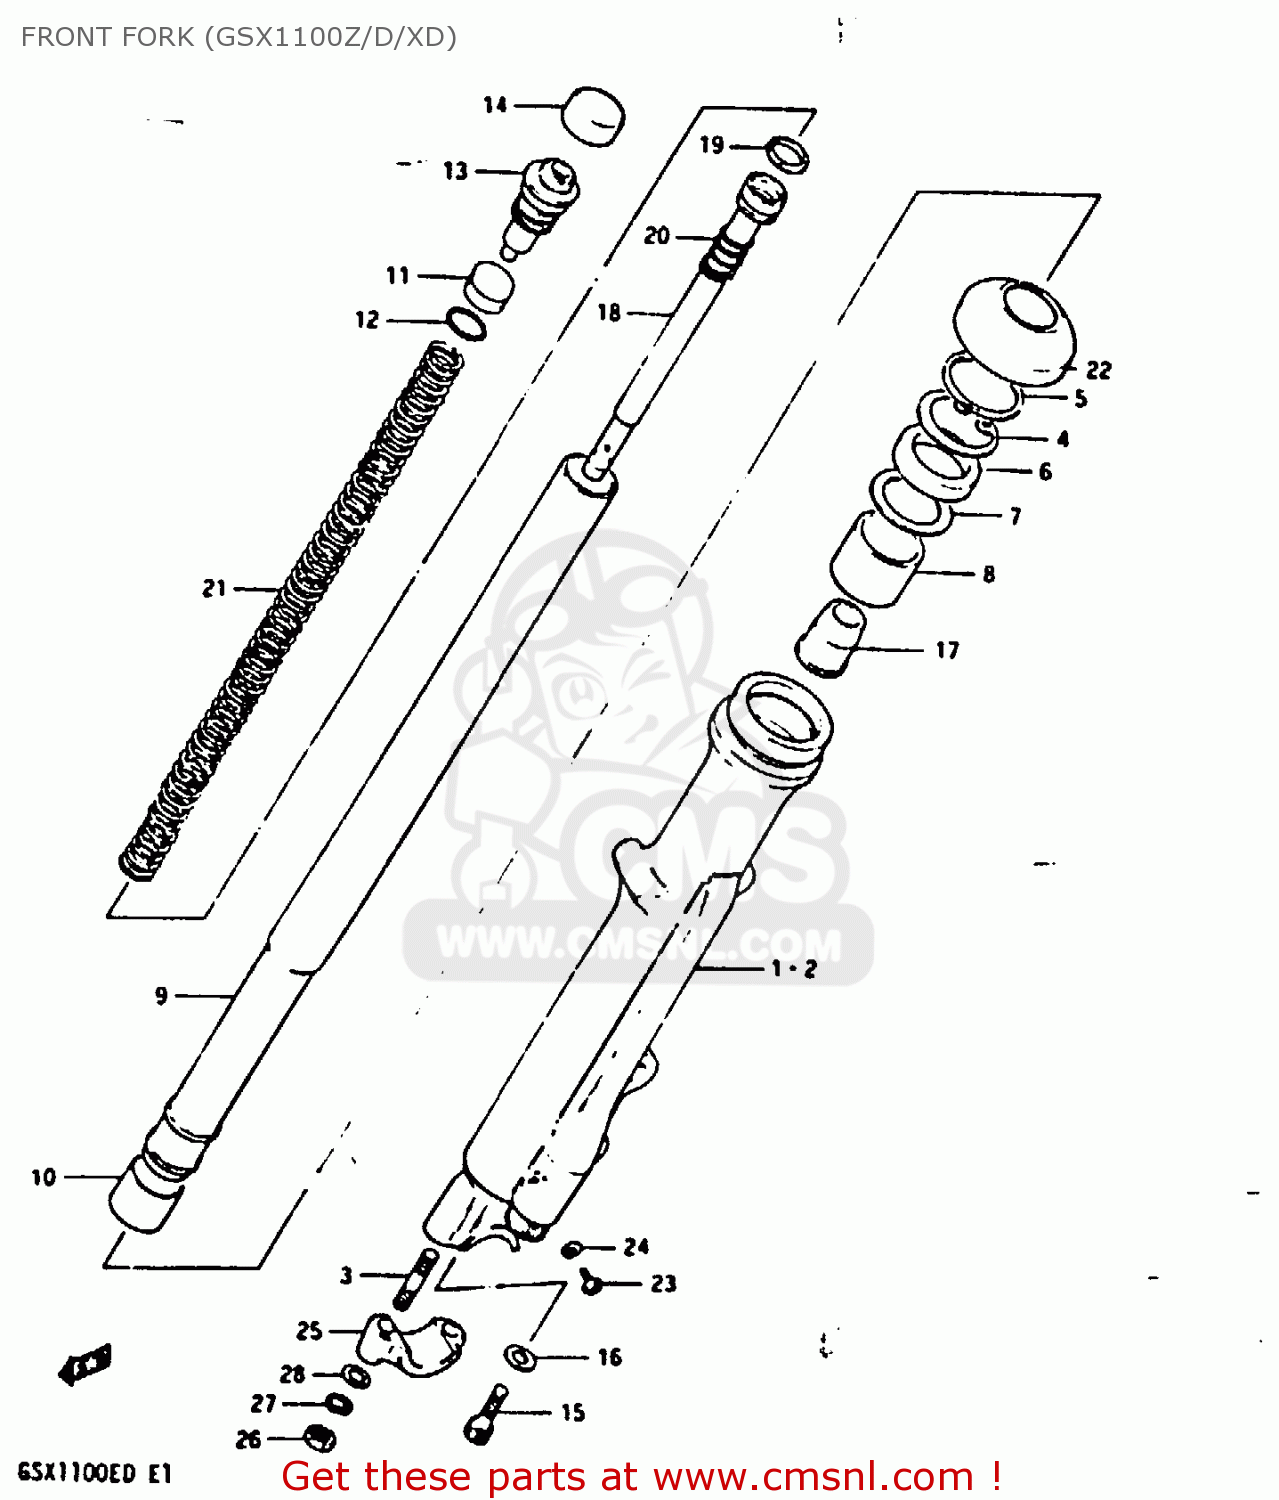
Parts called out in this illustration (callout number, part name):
1	OUTER TUBE, RH
2	OUTER TUBE, LH
3	STUD 8X30
4	RING,STOPPER
5	WASHER. FRONT FORK
6	OIL SEAL,FRONT FORK
7	WASHER
8	METAL,SLIDE
9	INNER TUBE
10	METAL,FRONT FORK PISTON
11	PISTON,FREE
12	O-RING
13	CAP
14	CAP,RUBBER
15	BOLT,FORK CYLINDER(10X25)
16	GASKET (NAS)
17	PIECE, OIL LOCK
18	CYLINDER
19	RING,PISTON
20	SPRING,FORK REBOUND
21	SPRING
22	SEAL,DUST
23	SCREW
24	GASKET,DRAIN,PLUG (NAS)
25	HOLDER,AXLE
26	NUT (8MM)
27	LOCK WASHER
28	WASHER
